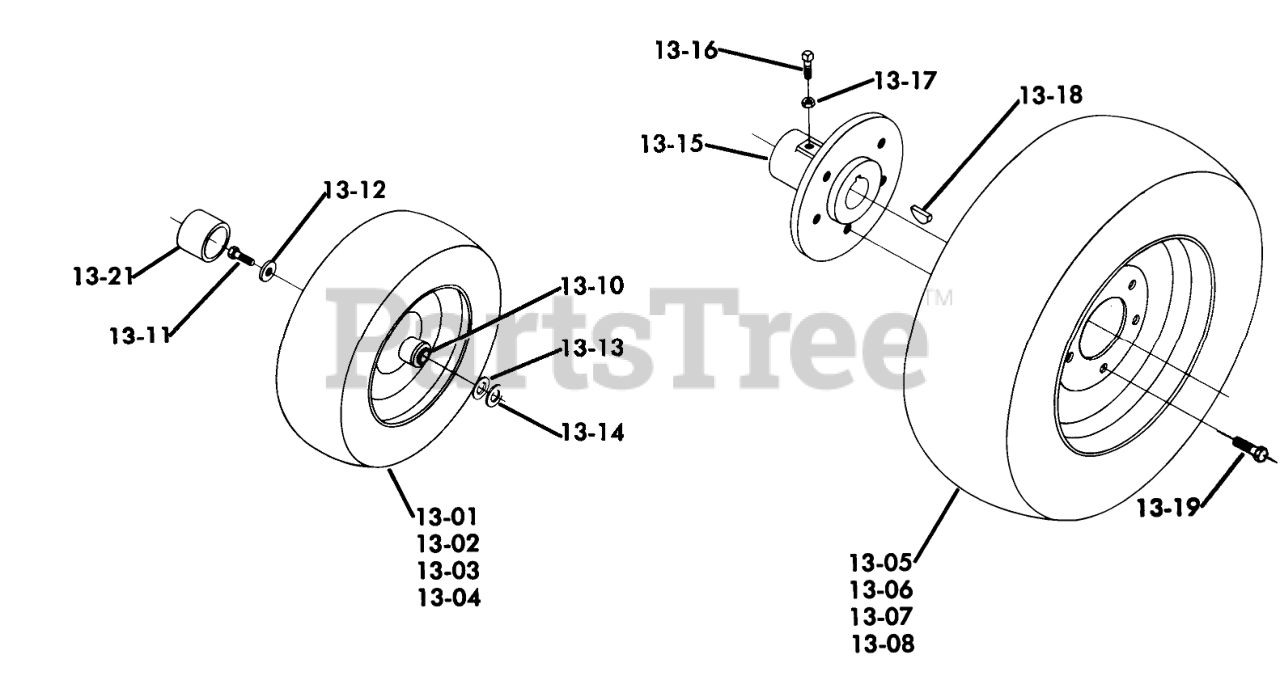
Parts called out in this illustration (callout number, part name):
13-01	ASSY-WHEEL & TIRE
13-02	WHEEL ASSY
13-03	TIRE TURF SAVER 16X6.50-8
13-04	Tube
13-05	Wheel and Tire
13-05	Tire & Wheel Assy
13-05	Wheel & Tire Assembly
13-06	Wheel
13-07	Tire
13-07	TIRE 22 X 7.50-12
13-07	Tire-Cleat, Rear
13-08	TUBE-INNER
13-09	VALVE
13-10	Bearing
13-11	Bolt
13-12	WASHER
13-13	WASHER
13-14	WASHER-SHIM
13-15	Hub Rear
13-16	Screw-Set
13-17	Nut
13-18	KEY-WOODRUFF
13-19	Lug Nut
13-21	HUB CAP
